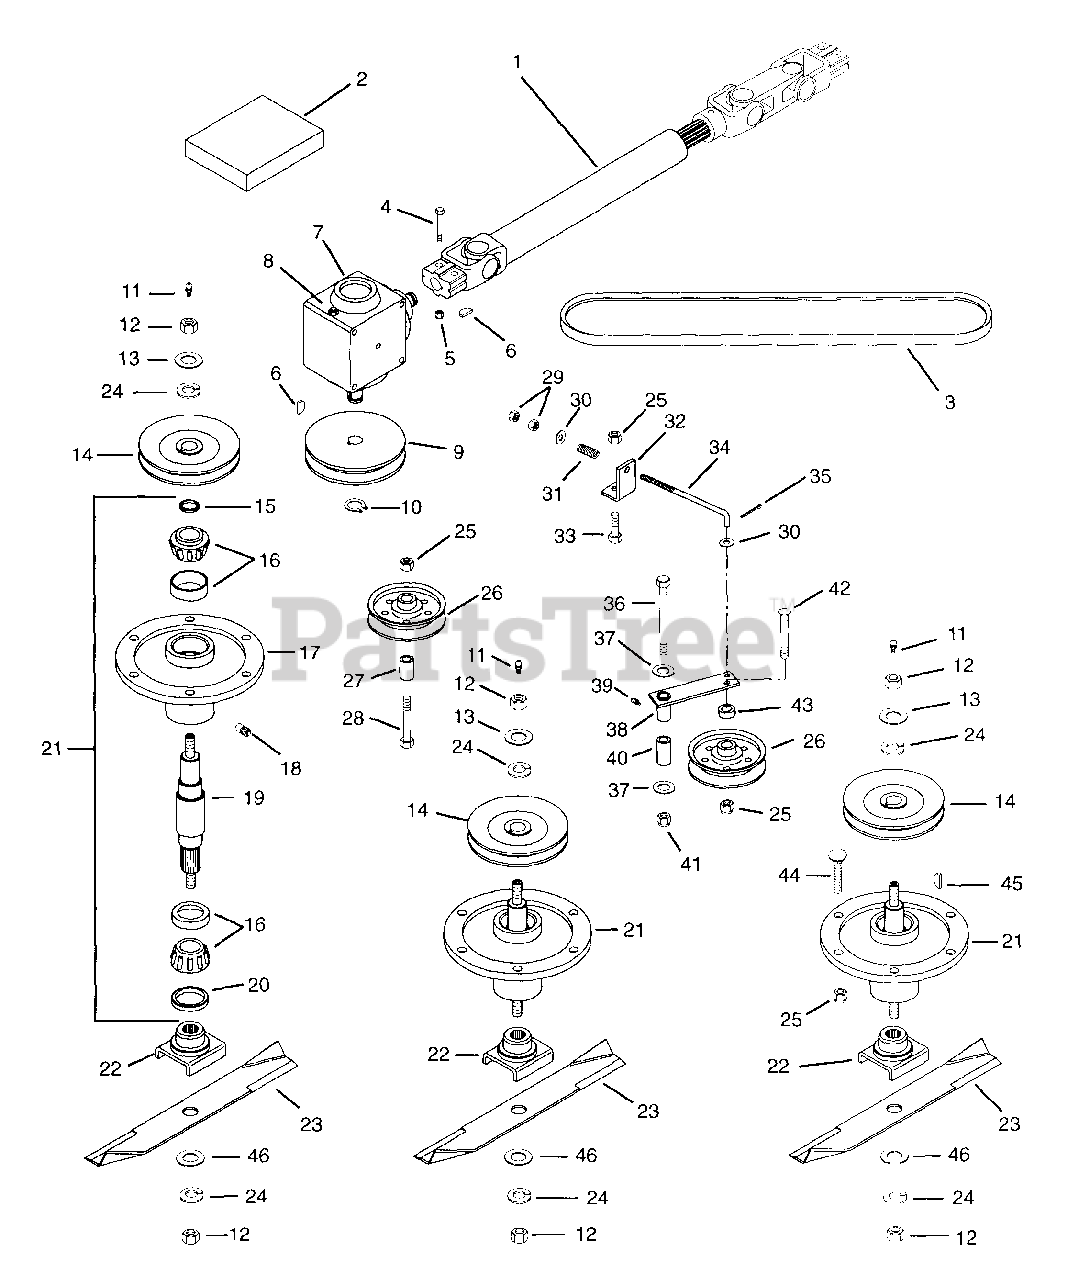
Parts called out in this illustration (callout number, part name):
1	C.V. Universal Joint - 60" Deck
1	C.V. Universal Joint Assembly
2	Kit, Repair, U-Joint
3	V-Belt B-Section 82.375 x .672
3	V-Belt A-Section 94.8 x .656
4	Bolt-Hex .31-18 x 1.75 Grade 5
5	Nut-Locking-Nylon .312-18 Grade 2
6	Key, Woodruff .25 x .875
7	Gearbox, Right Angle 1:1
8	Plug, 1/8 Vent
9	Sheave, Gear Box
10	Ring-Retaining-External .821 x .078
11	Fitting-Lube 1/8
12	Nut-Hex .625-11 Grade 2
13	Washer-Flat-Steel .687 x 1.312 x 1.50
14	Weldment, Spindle Sheave
15	Seal 1.987 x 1.500 x .313
16	Assembly, Bearing Cup & Cone
17	Bearing, Housing
18	Relief Fitting
19	Shaft, Spindle
20	Seal 1.987 x 1.375 x .313
21	Service Kit Spindle Assembly
22	Weldment, Blade Cradle
23	Blade
23	Blade, 72" Mower
24	Washer - Lock .625 x .156
25	Nut-Locking-Nylon .375-16 Grade 2
26	Idler-Flat-Pulley 6.75 x .510
27	Spacer .562 x .975 x 1.00
27	Spacer .516 x .875 x .300
28	Bolt-Hex .50-13 x 2.75 Grade 5
28	Bolt-Hex .50-13 x 2.00 Grade 5
29	Nut-Hex .375-24 Grade 2
30	Washer-Flat-Steel .406 x .812 x .062
31	Spring-Compression .125 x .78 x 1.00
32	Support, Spring
33	Bolt-Hex .38-16 x 1.00 Grade 5
34	Rod, Idler
35	Pin-Cotter .09 x .75
36	Bolt-Hex .50-13 x 3.375
37	Washer-Flat-Steel .500 x 1.250 x .083
38	Weldment, Idler Pivot
39	Fitting-Lube .25-28 x .256
40	Spacer .505 x .855 x 2.50
41	Nut-Locking .50-13 Grade 5
42	Bolt-Hex .38 x 1.75 Grade 5
43	Spacer .516 x .875 x .300
44	Bolt-Round Head Square Neck .38-16 x 1.50
45	Key-Woodruff .25 x 1
46	Washer-Flat-Steel .656 x 1.312 x .095
